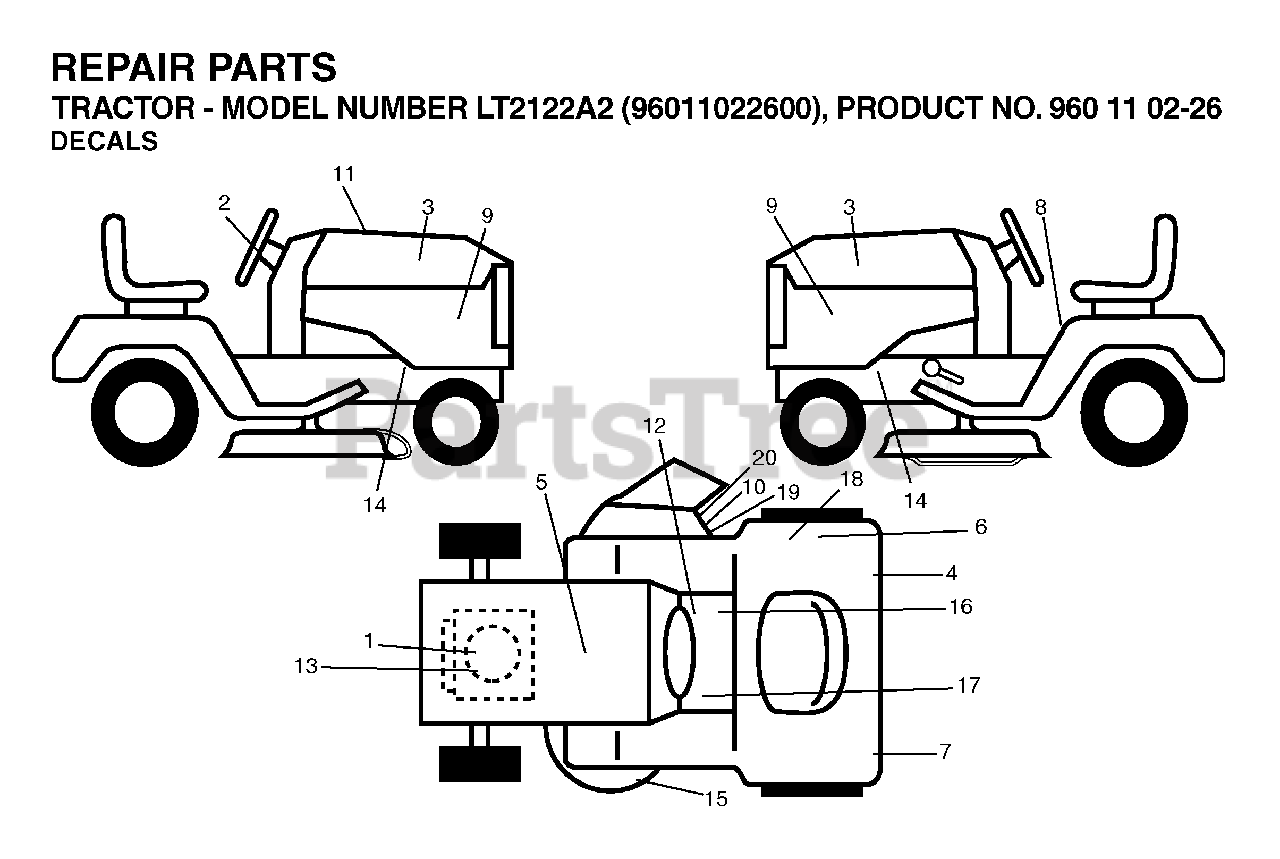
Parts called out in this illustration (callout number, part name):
5	DECAL BTRY SYMBOLS
6	DECAL.80 DBA.AUSTRALIA
10	DECAL.INTERNATIONL.CUTFINGER
12	DECAL PARK BRAKE
13	DECAL.B&S.22HP#275796
15	DECAL V-BELT SCHEMATIC
19	DECAL, DEFLECT WARNING
